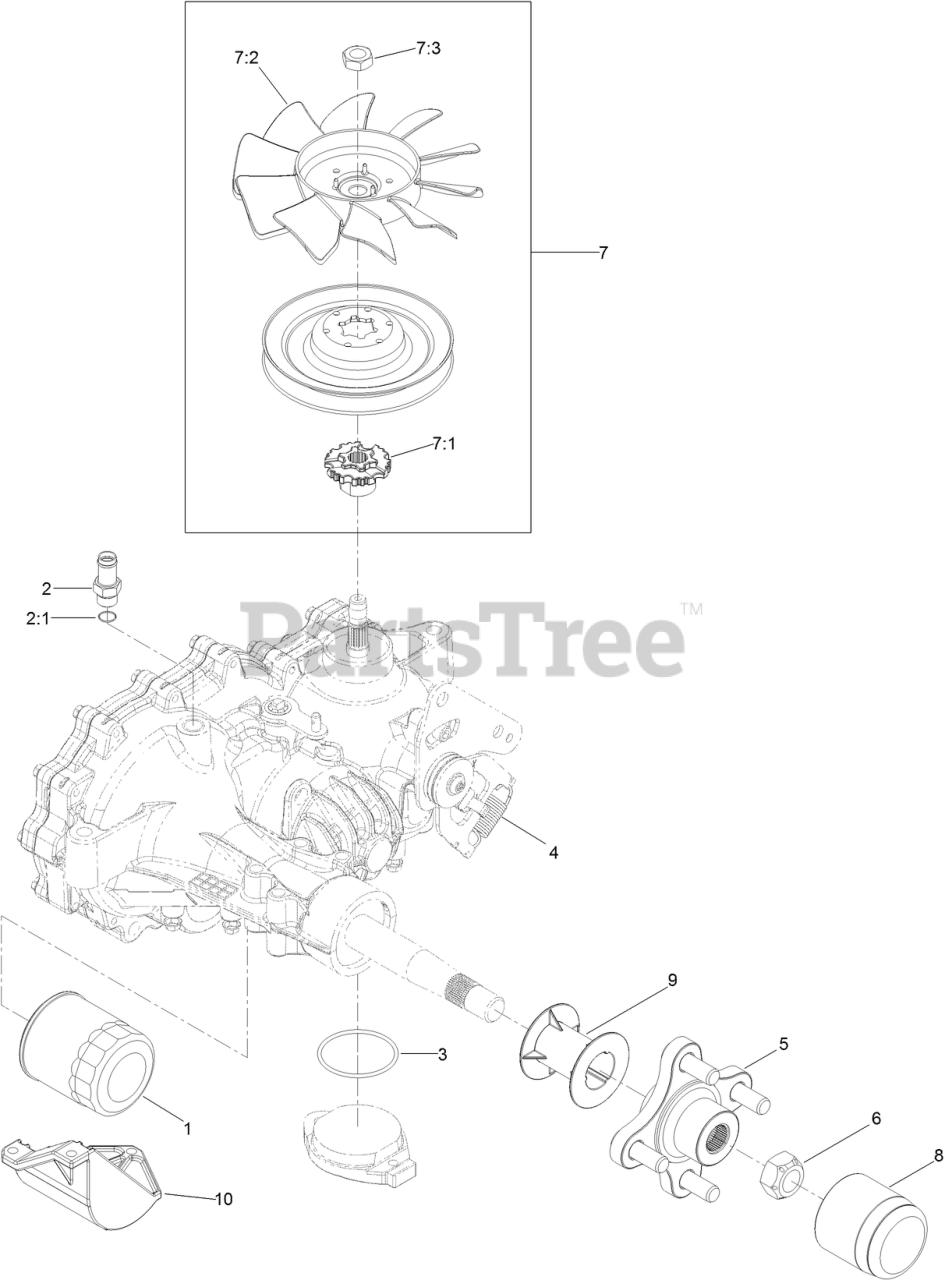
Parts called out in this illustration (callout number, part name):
1	ELEMENT-OIL FILTER, HYD
2	ADAPTER-STRAIGHT
2:1	O-RING
3	O RING-SEAL
4	SPRING-EXTENSION
5	HUB-OFFSET
6	NUT-HUB
7	FAN AND PULLEY KIT
7:1	HUB-FAN
7:3	NUT-HJ
8	CAP-AXLE, LONG
9	TUBE-AXLE
10	GUARD-FILTER, RH
